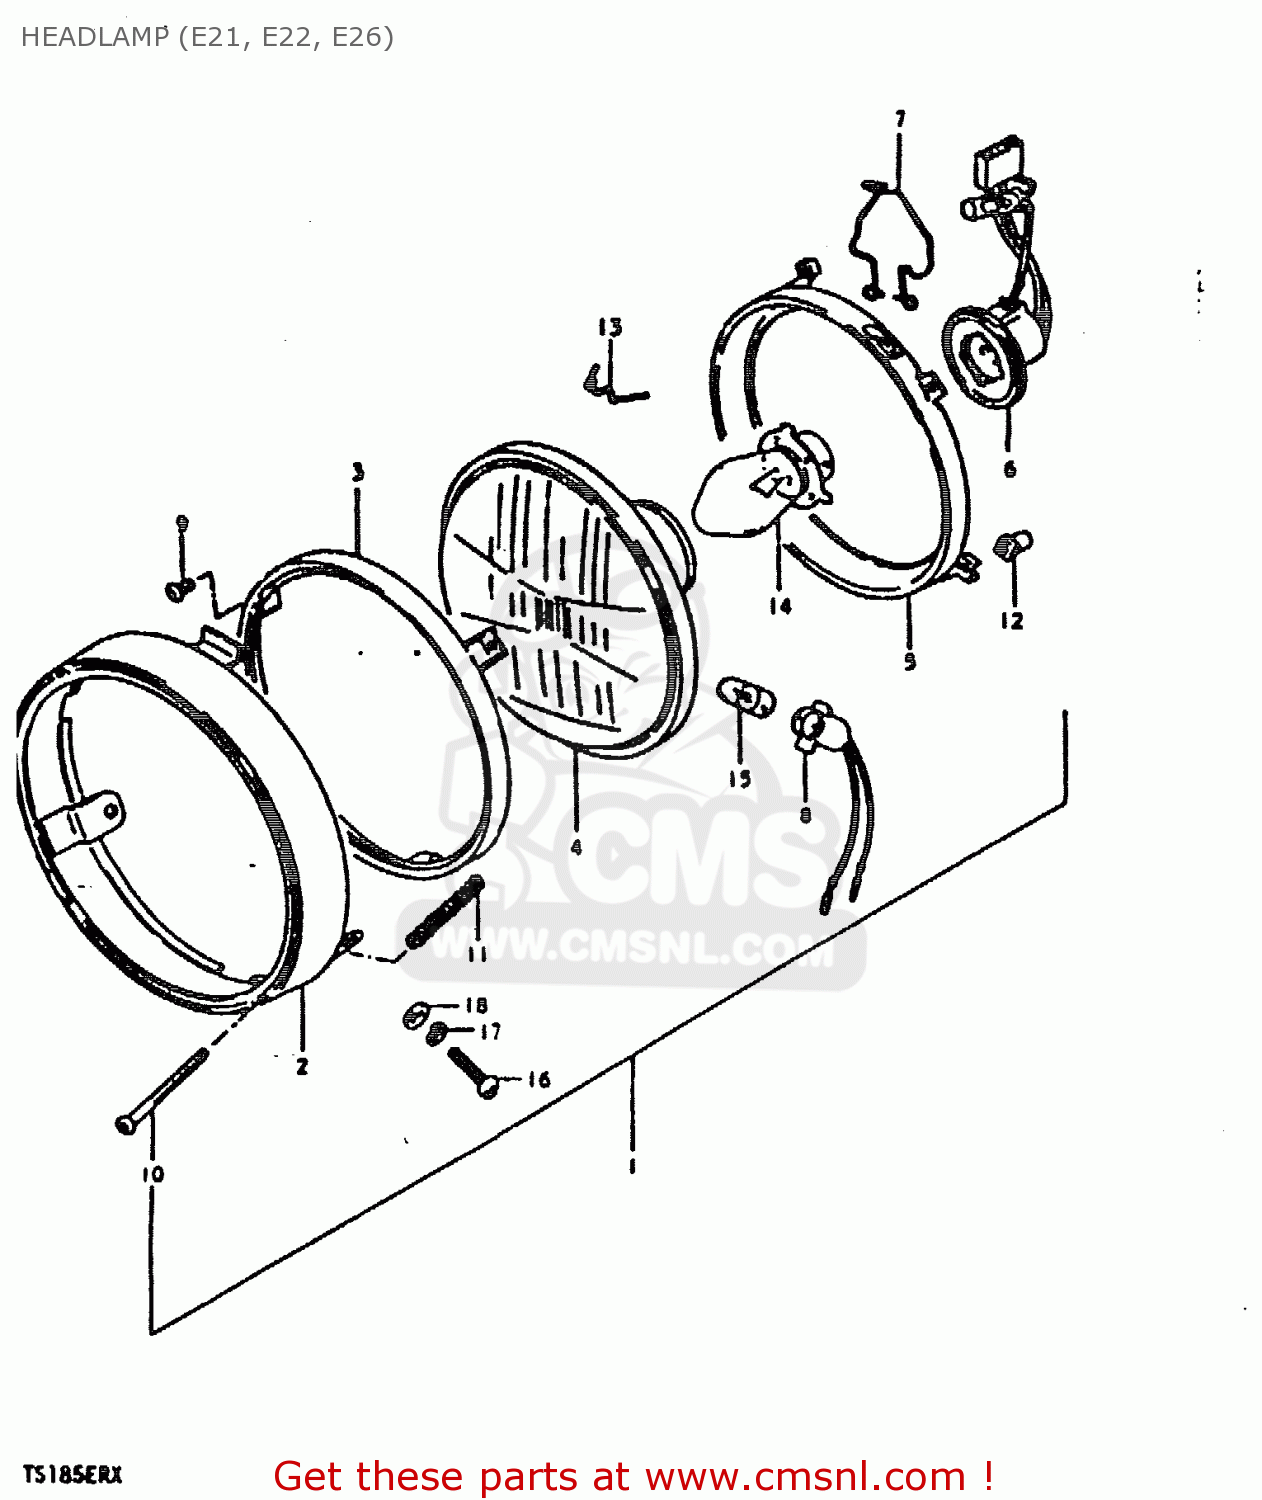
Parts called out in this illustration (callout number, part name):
1	HEADLAMP ASSY
2	RIM
3	RETAINER,HEADLAMP
4	UNIT
5	RING, MOUNTING
6	SOCKET
7	CLAMP,HEADLAMP
8	SOCKET
9	SCREW
10	SCREW,HEADLAMP ADJUST
11	SPRING,ADJUSTING
12	NUT,HEADLAMP ADJUSTER
13	SPRING,HEADLAMP UNIT
14	BULB (6V,25/25W)
15	BULB(6V4W,STANLEY,A1364J)
16	SCREW
17	LOCK WASHER
18	WASHER
